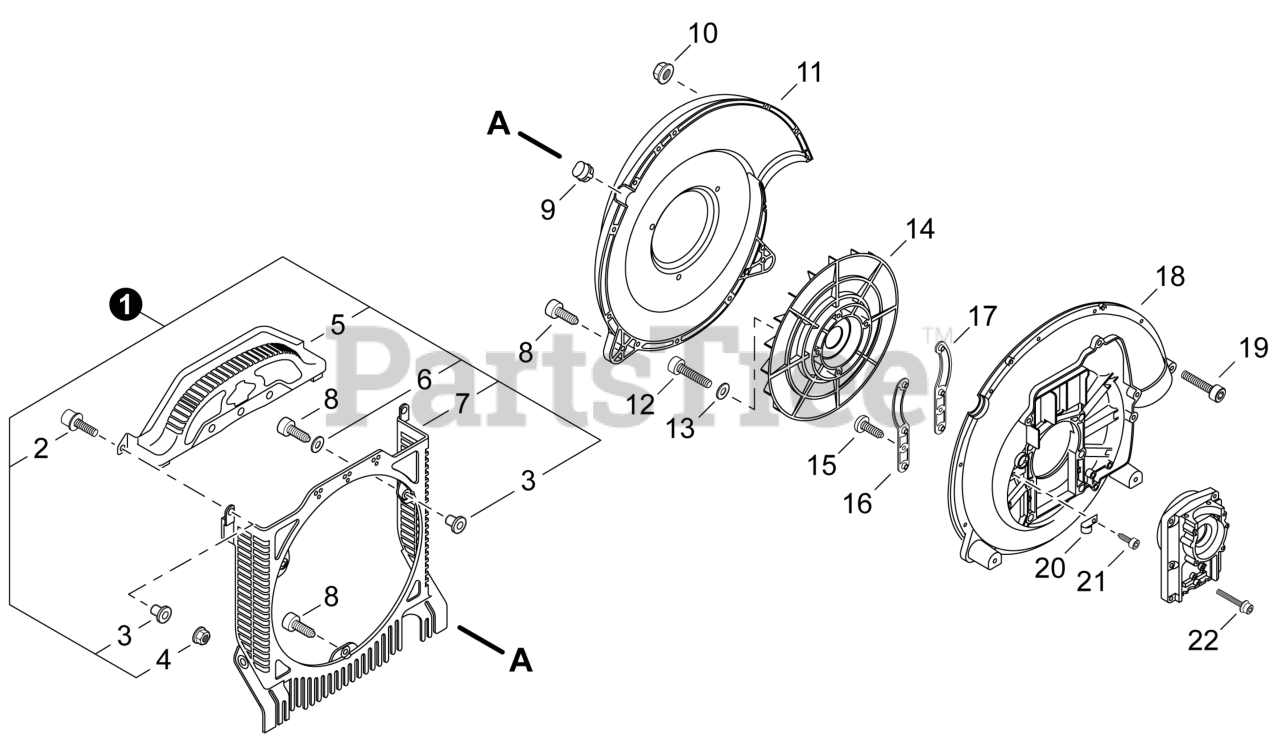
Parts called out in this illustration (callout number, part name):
1	GUARD KIT, DEBRIS
2	BOLT 5x20
4	NUT, LOCK M5
5	SHIELD, DEBRIS - UPPER
6	WASHER 5.5x16x2T
7	SHIELD, DEBRIS - LOWER
8	SCREW, TAPPING 5x20
9	PLUG, FAN CASE
10	NUT, FLANGE M5
11	COVER, FAN
12	BOLT 6x35
14	FAN, BLOWER
15	SCREW 5x14
16	PLATE, ENGINE (A)
17	PLATE, ENGINE (B)
18	CASE, FAN
19	BOLT 5x60
21	SCREW, TAPPING 5x16
22	SCREW 6x35
